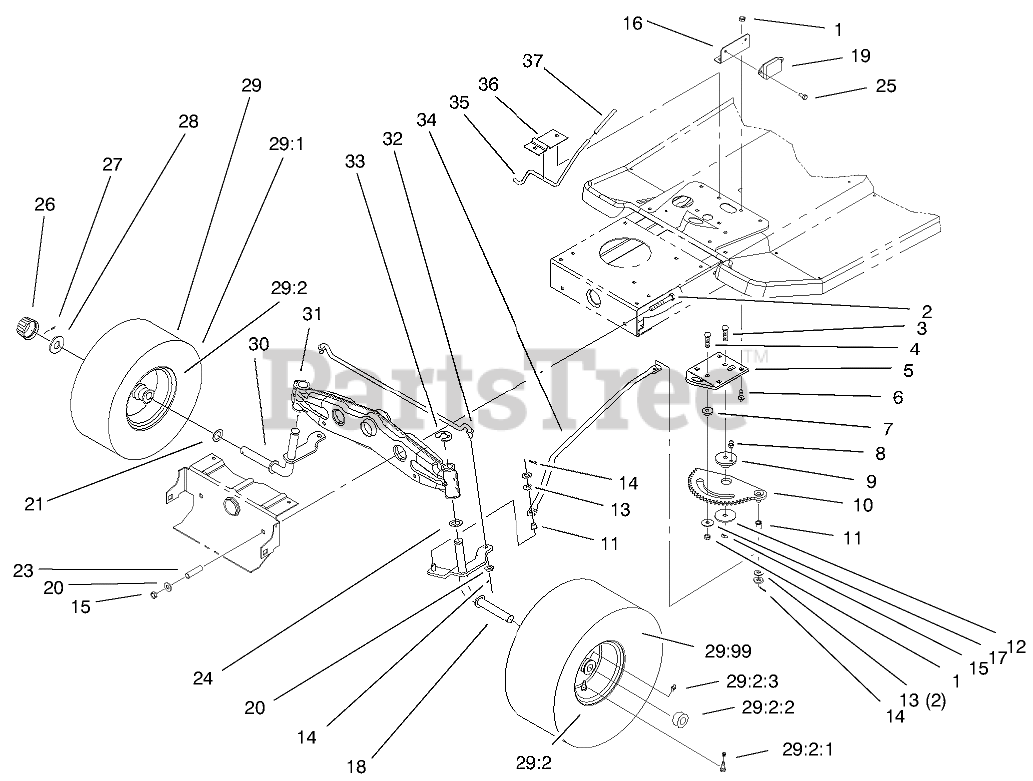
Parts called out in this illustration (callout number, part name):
1	NUT-LOCK, NI
2	SCREW-HH
3	SCREW-CARR
4	SCREW-CARR
5	BRACKET-RACK, STEERING
6	BOLT-CARR
7	SPACER-RACK, STEERING
8	FITTING-GREASE
9	BUSHING-ECCENTRIC
10	RACK-STEERING
11	BUSHING-FLANGED, NYLON
12	WASHER-BEARING
13	WASHER-FLAT
14	PIN-COTTER
15	NUT-LOCK, NI
16	BRACKET-MODULE
17	WASHER-PIVOT
18	LH Spindle Wa (Only On: 71198)
19	MODULE
20	WASHER-FLAT
21	WASHER-THRUST
23	SPACER
24	WASHER-THRUST
25	SCREW-HWH
26	CAP-HUB
27	PIN-COTTER
28	WASHER-PLAIN
29	Wheel & Tire ASM Front
29:1	Tire (Only On: Serial No. 990001-9905000)
29:1	Tire (Only On: Serial No. 9905001 & Up)
29:2	RIM ASM
29:2:1	Stem-Valve
29:2:2	BEARING-WHEEL
29:2:3	FITTING-GREASE
29:99	TUBE-INNER
30	RH SPINDLE ASM
31	FRONT AXLE ASM
32	TIE ROD-STEERING
33	E-RING
34	LINK-DRAG
35	ROD-BRAKE, PARKING
36	BRACKET-PARKING BRAKE
37	GRIP-BRAKE, PARKING
